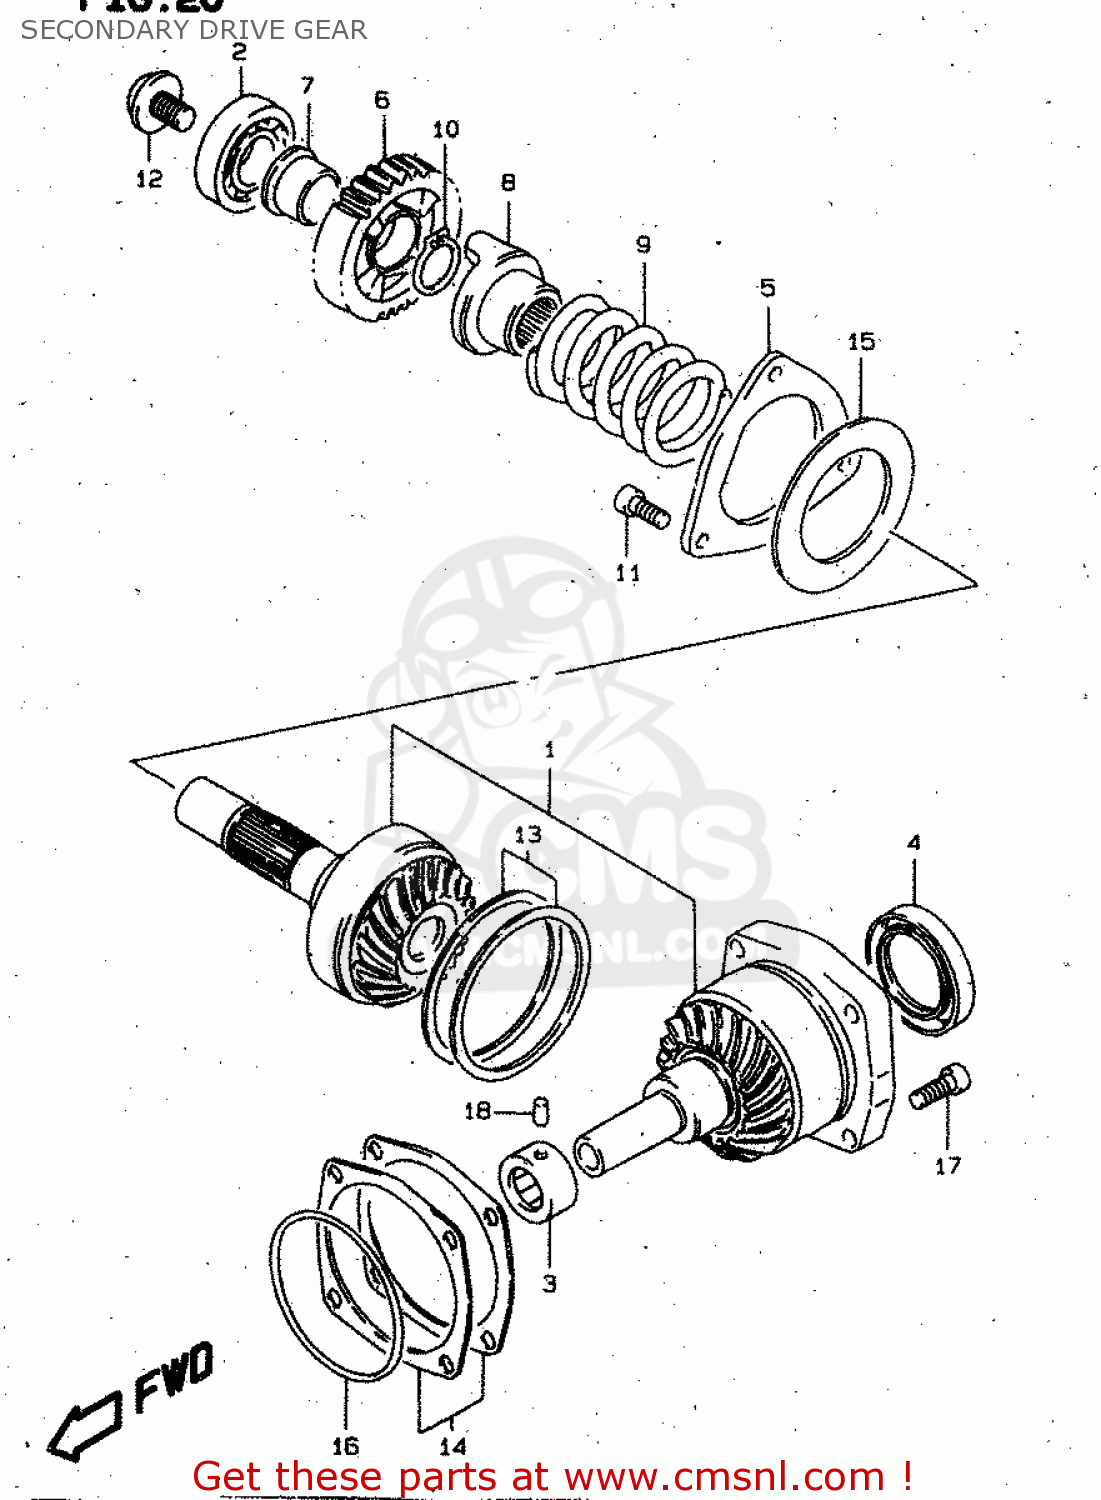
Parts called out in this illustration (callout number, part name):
1	GEAR & HOUSING SET,SECONDARY
2	BEARING(25X62X17)
3	BEARING(20X34X16)
4	SEAL,OIL(44X68X8)
5	STOPPER,SEC DRIVE BEARING
6	GEAR,OVER DRIVING DRIVEN
7	BUSHING,OD DRIVEN GEAR
8	DOG,OUTPUT CAM
9	SPRING
10	CIRCLIP
11	BOLT
12	BOLT(14X21)
13	SHIM SET,SEC DRIVE
14	SHIM SET,SEC DRIVEN
15	WASHER(57X90X3)
16	O RING(D:3.7,ID:76.5)
17	BOLT
18	PIN
